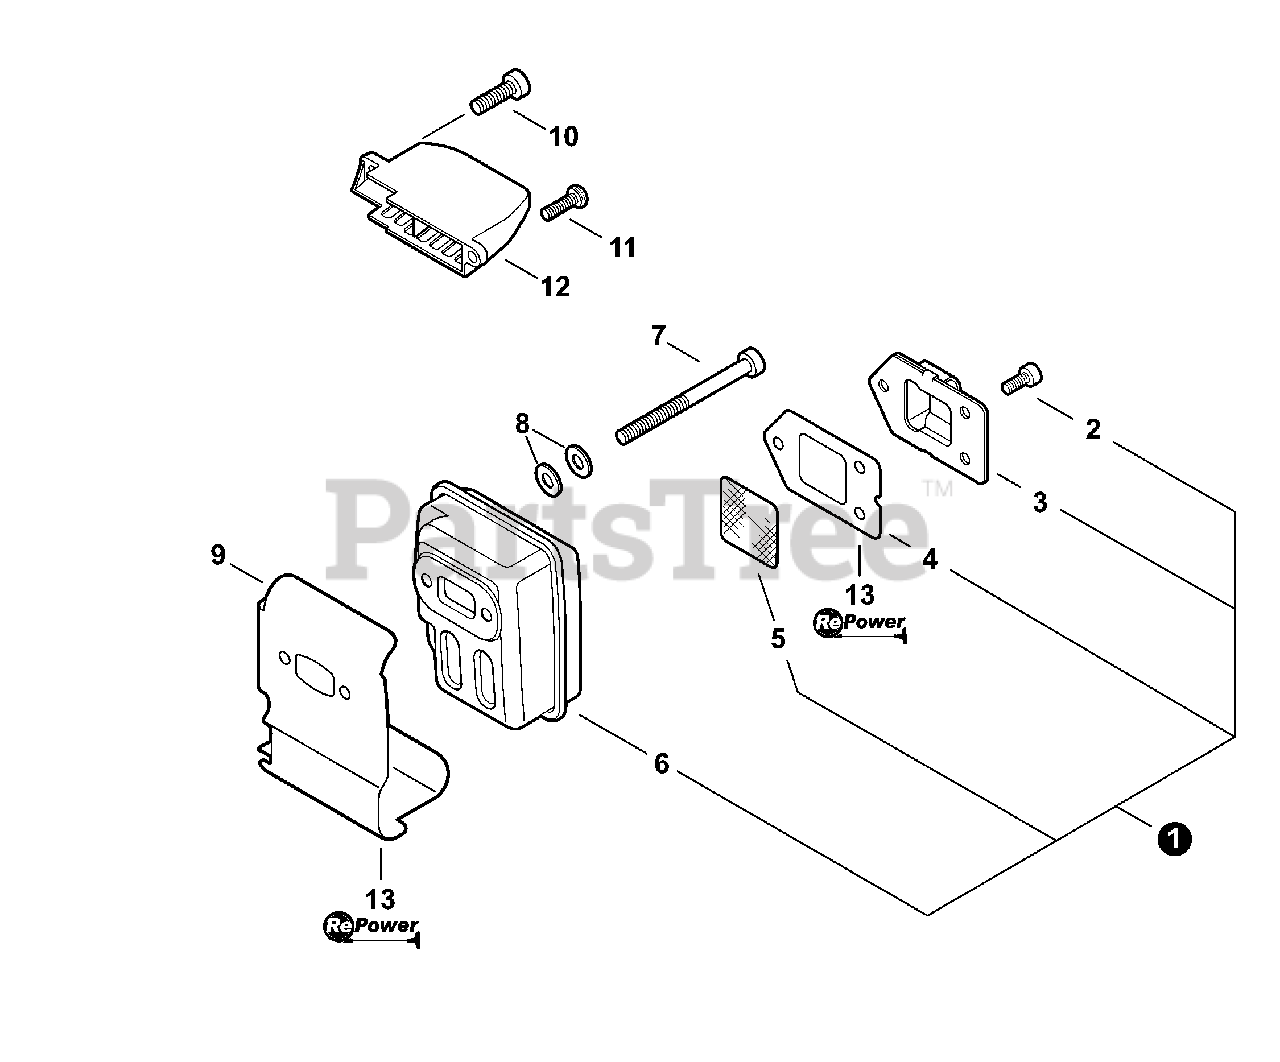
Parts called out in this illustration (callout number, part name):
1	MUFFLER ASSY
2	SCREW - 4×8 -- TORX
3	GUIDE, EXHAUST
4	GASKET, EXHAUST
5	SCREEN, SPARK ARRESTER
7	SCREW - 5×55
8	WASHER - CONICAL
9	SHIELD, EXHAUST
10	SCREW - 5×16
11	SCREW - 5×16
12	DUCT, AIR
13	GASKET KIT
